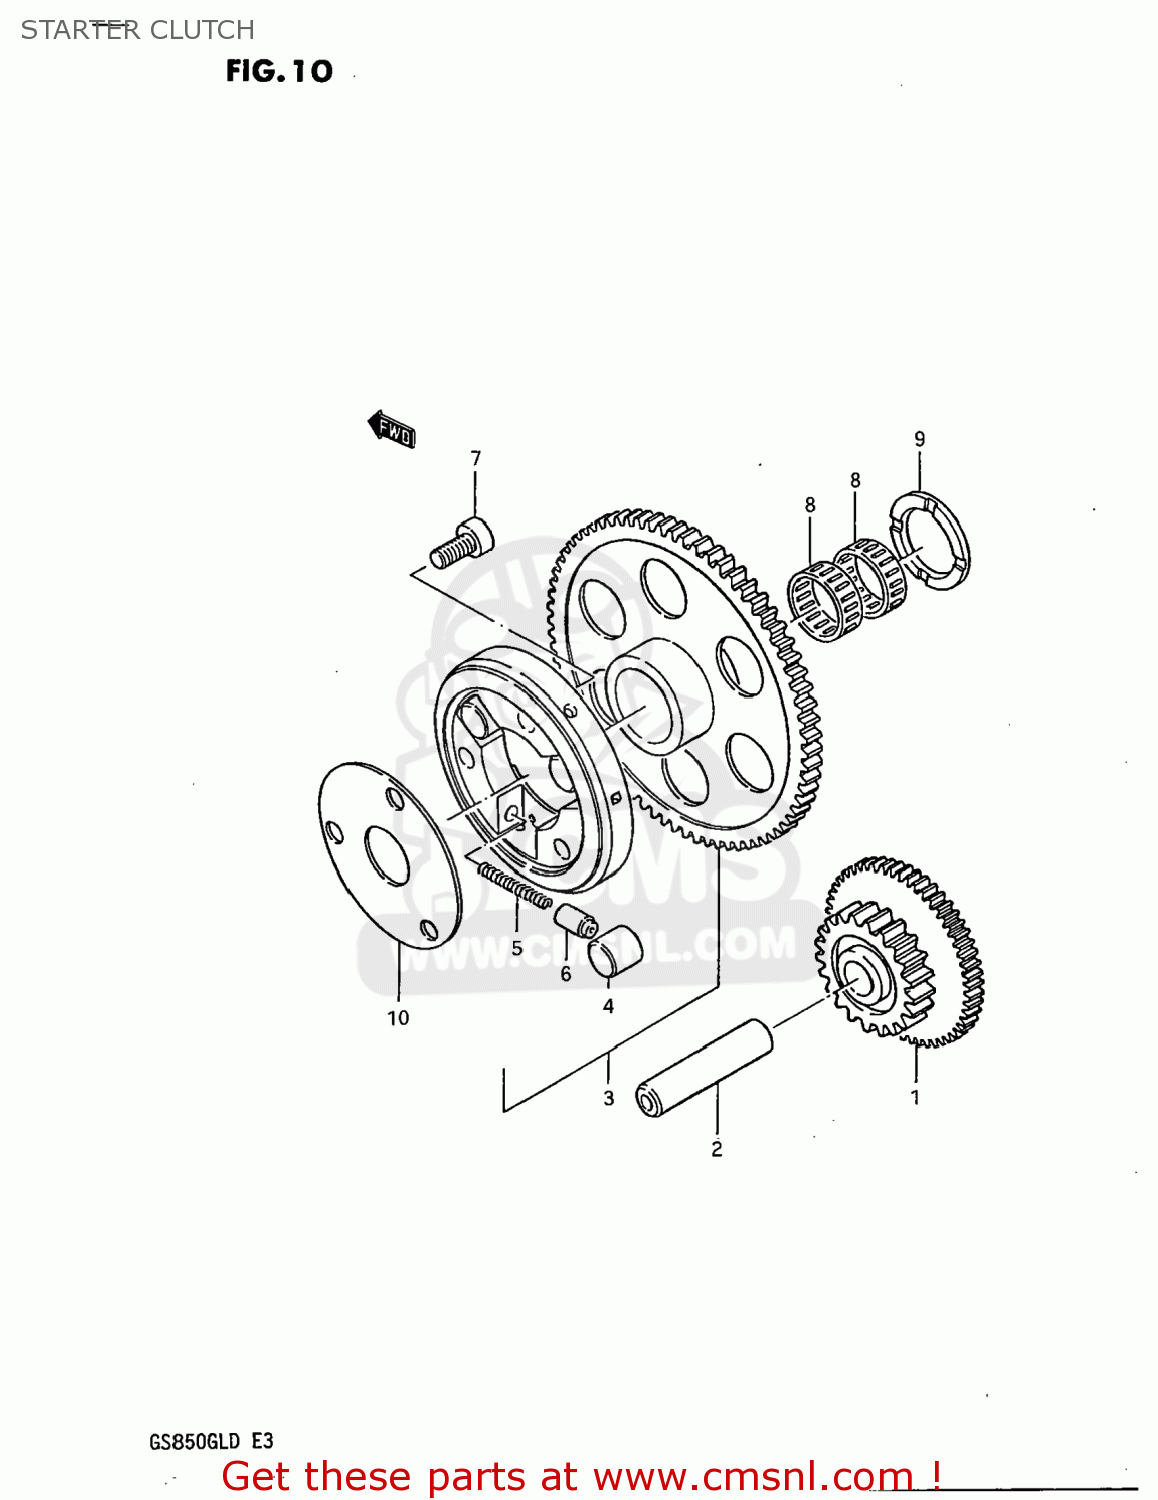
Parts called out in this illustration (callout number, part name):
1	GEAR,STARTER IDLE
2	PIN(7.4X13X61)
3	CLUTCH SET,STARTER
4	ROLLER(15X13)
5	SPRING
6	PIECE,PUSH
7	BOLT
8	BEARING(25X29X9.9)
9	WASHER(25X38X2.5)
10	SHIM,STARTER CLUTCH HUB
